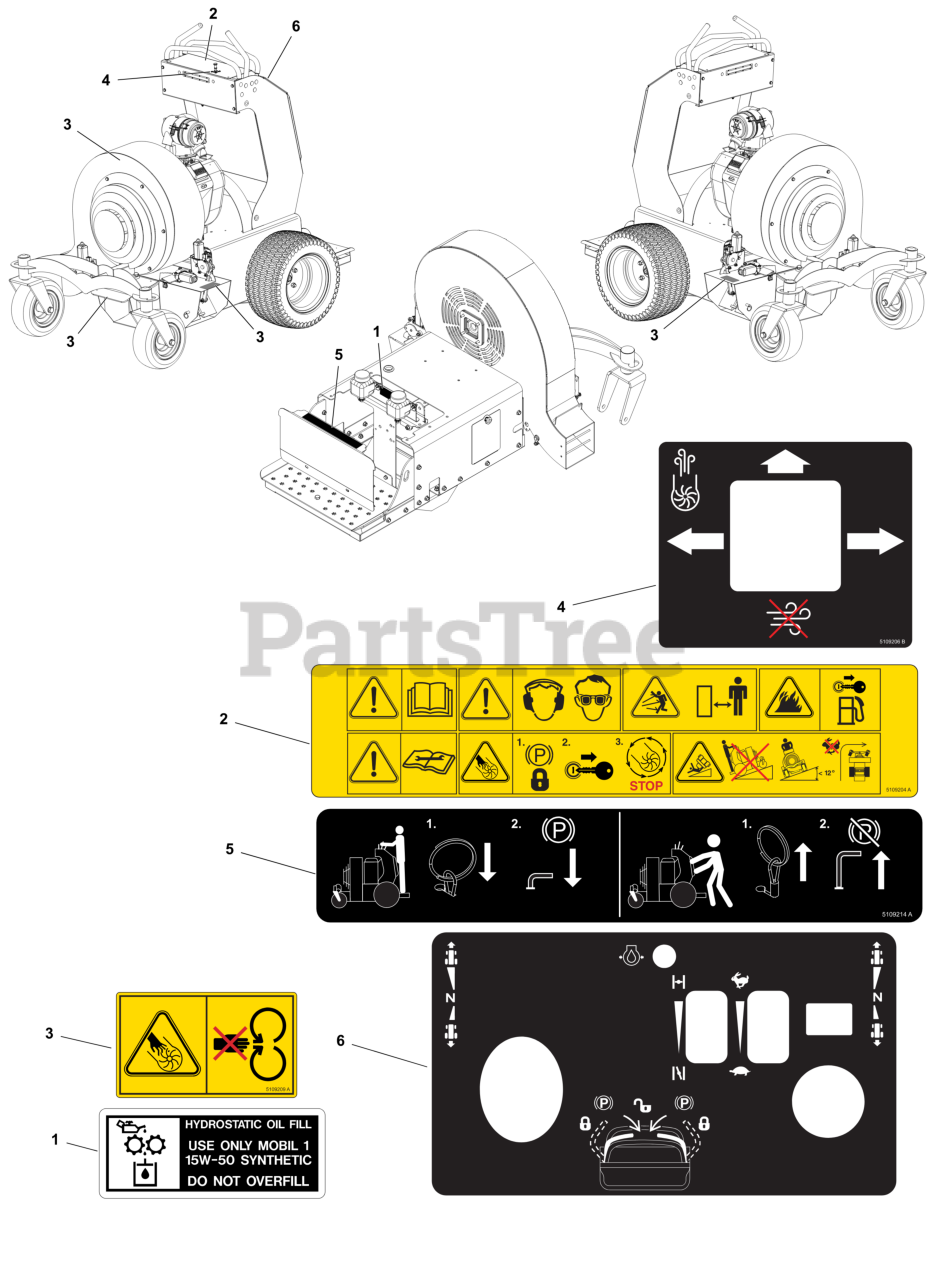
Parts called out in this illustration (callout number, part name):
2	DECAL, Warning/Safety
3	DECAL, DANGER
5	DECAL, BRAKE, PARK
6	DECAL, Controls
